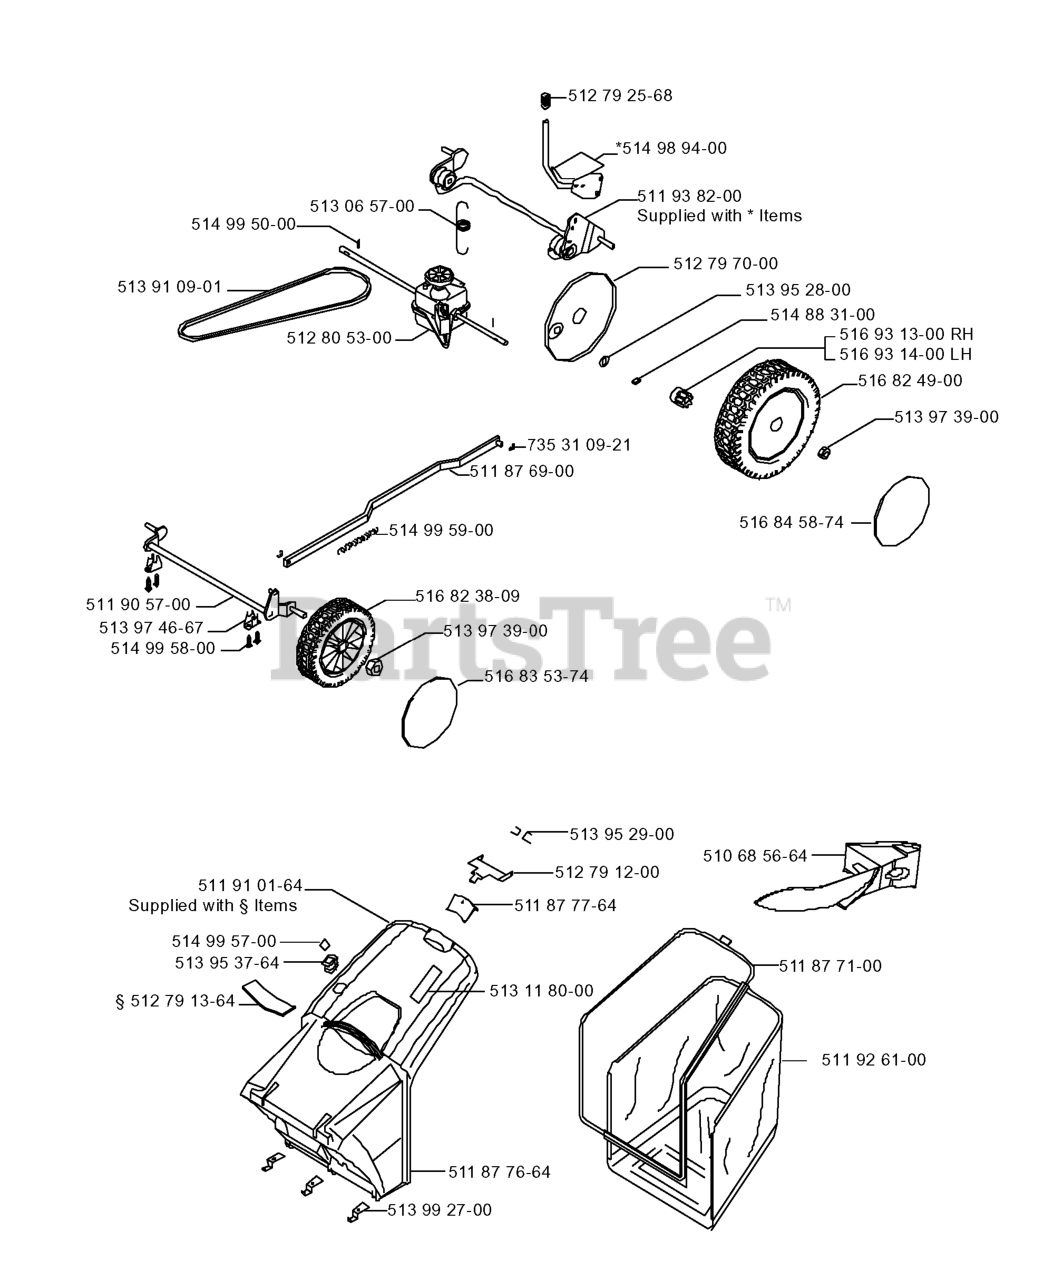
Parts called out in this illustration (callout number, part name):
2	DRAWBAR
3	SCREW 3/8-16X3/4
5	BUMPER DASH
6	PLATE
8	CLIP,INSULATOR
10	BOLT D
11	PANEL.DASH.LH.LTX
13	PANEL ASM, DASH RH
15	Screw, Machine, Truss Head 5/16-18 UNC x 3/4
16	NUT
17	HOOD
18	BUMPER.HOOD.TEX.HUSQVARNA
25	WASHER
26	NUT
28	RP GRILLE/LENS ASM.
30	CONSOLE.CRD.AUTO.GRY
31	BRACKET SUPPORT FENDER
33	FOOTREST PNT LH
34	FOOTREST PNT RH
37	Screw 5/16-18 x 1/2 Hex, Self Tapping 5/16-18 x 1/2
38	BRACKET ASM PIVOT MOWER REAR
39	BRACKET PIVOT
69	SCREW.HI-LO.CONSOLE
145	ROD PIVOT CHASSIS/HOOD
162	BRACKET
163	BRACKET EXTEN CHASSIS RH CRD
165	RP.COVER.BATTERY.CRD.GREY
172	WASHER
175	DOOR TRAP
179	ROD PIVOT FBI
184	BRACKET.ACTUATOR.BAGGER.SRD
186	LATCH ASSY
187	WELDNUT
189	LOCKWASHER #10
190	SCREW
207	SCREW, 5/16-18 X 1/2
208	SCREW 3/8-16X1/2
209	SCREW, 3/8-16X3/4
212	INSERT REFLECTIVE
213	SKIRT SIDE LH
214	SKIRT SIDE RH
216	SCREW HEXWSHR 1/4-20X3/4
256	COVER FENDER CRD
258	LENS.HUSQVARNA LT.RH
259	LENS.HUSQVARNA LT.LH
265	SEALING
266	SEALING
272	VENT SIDE HOOD RH
273	VENT SIDE HOOD LH
278	SCREW
295	VENT TOP HOOD
296	TRIM
297	CLIP.RETAINER.TINNER.
298	NUT PUSH M
299	RP LOGO
